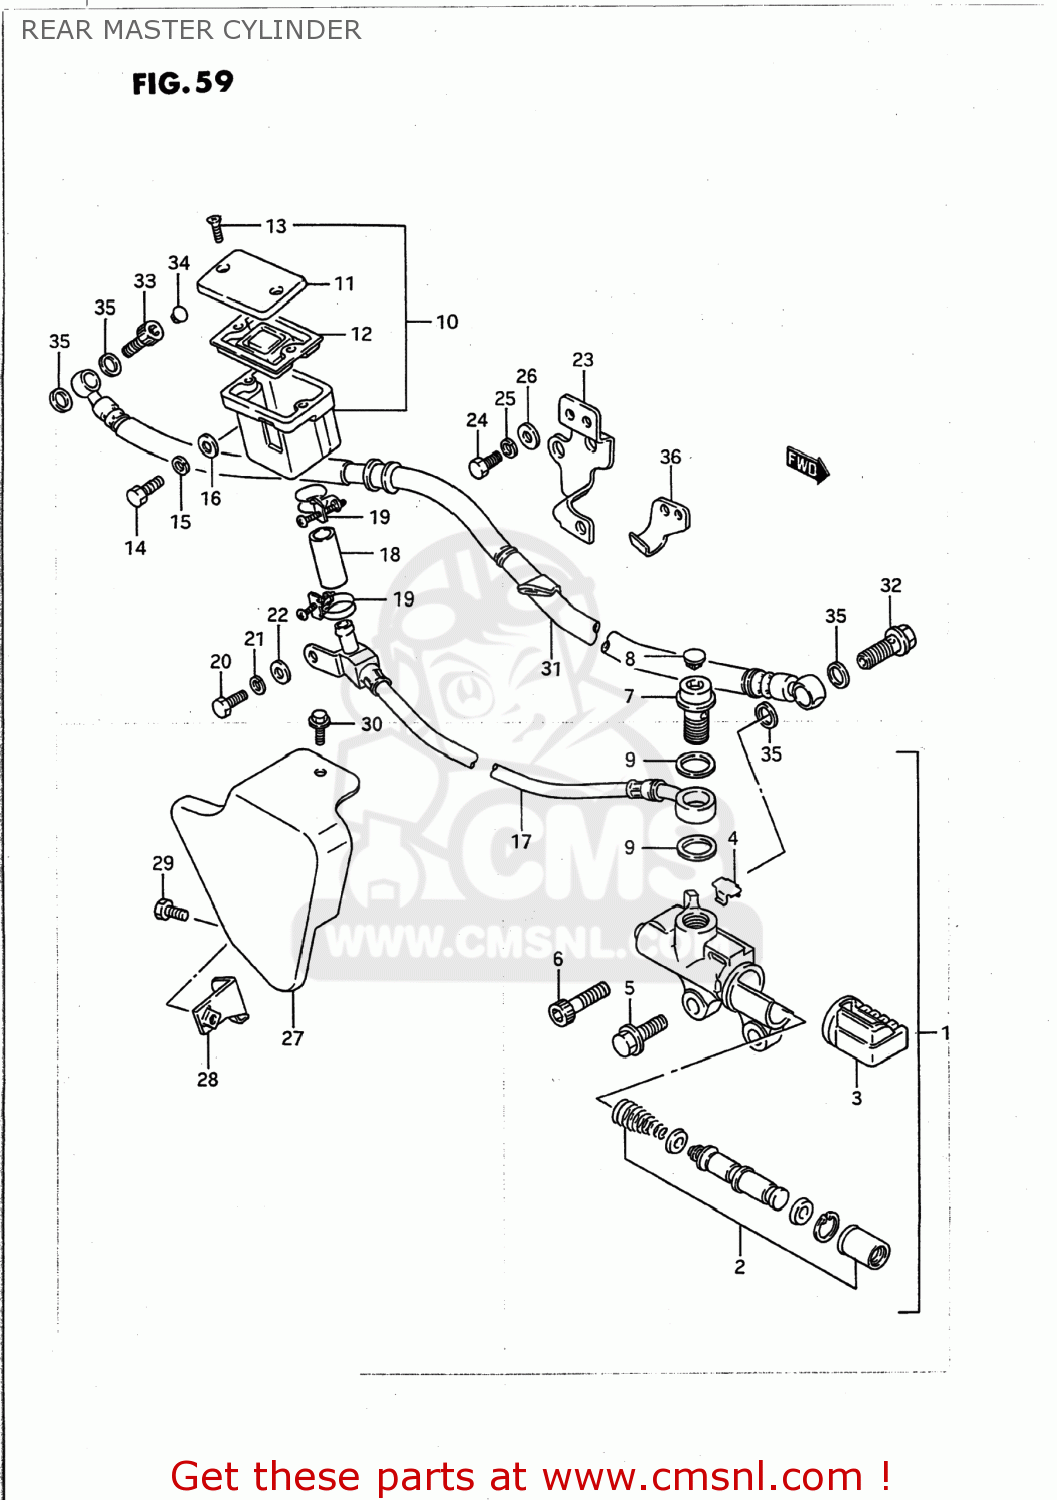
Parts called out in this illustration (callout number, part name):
1	CYLINDER ASSY,RR MASTER
2	PISTON/CUP SET
3	BOOT
4	PLATE,STOP
5	BOLT
6	BOLT(8X30)
7	BOLT,BRAKE FLUID
8	CAP(OD:12)
9	WASHER,BRAKE FLUID
10	TANK ASSEMBLY,RESERVOIR
11	CAP
12	DIAPHRAGM
13	SCREW
14	BOLT
15	WASHER,LOCK
16	WASHER
17	HOSE,RESERVOIR TANK
18	HOSE,RESERVOIR TANK
19	CLAMP
20	BOLT
21	WASHER,LOCK
22	WASHER
23	BRACKET,RESERVOIR TANK
24	BOLT
25	LOCK WASHER
26	WASHER
27	COVER,RESERVOIR TANK
28	BRACKET COMP,RESERVOIR TANK
29	SCREW(6X10)
30	BOLT
31	HOSE,REAR BRAKE
32	BOLT UNION
33	BOLT UNION
34	CAP(OD:12)
35	WASHER(10X15X1.5)
36	CLAMP,RR BRAKE HOSE
